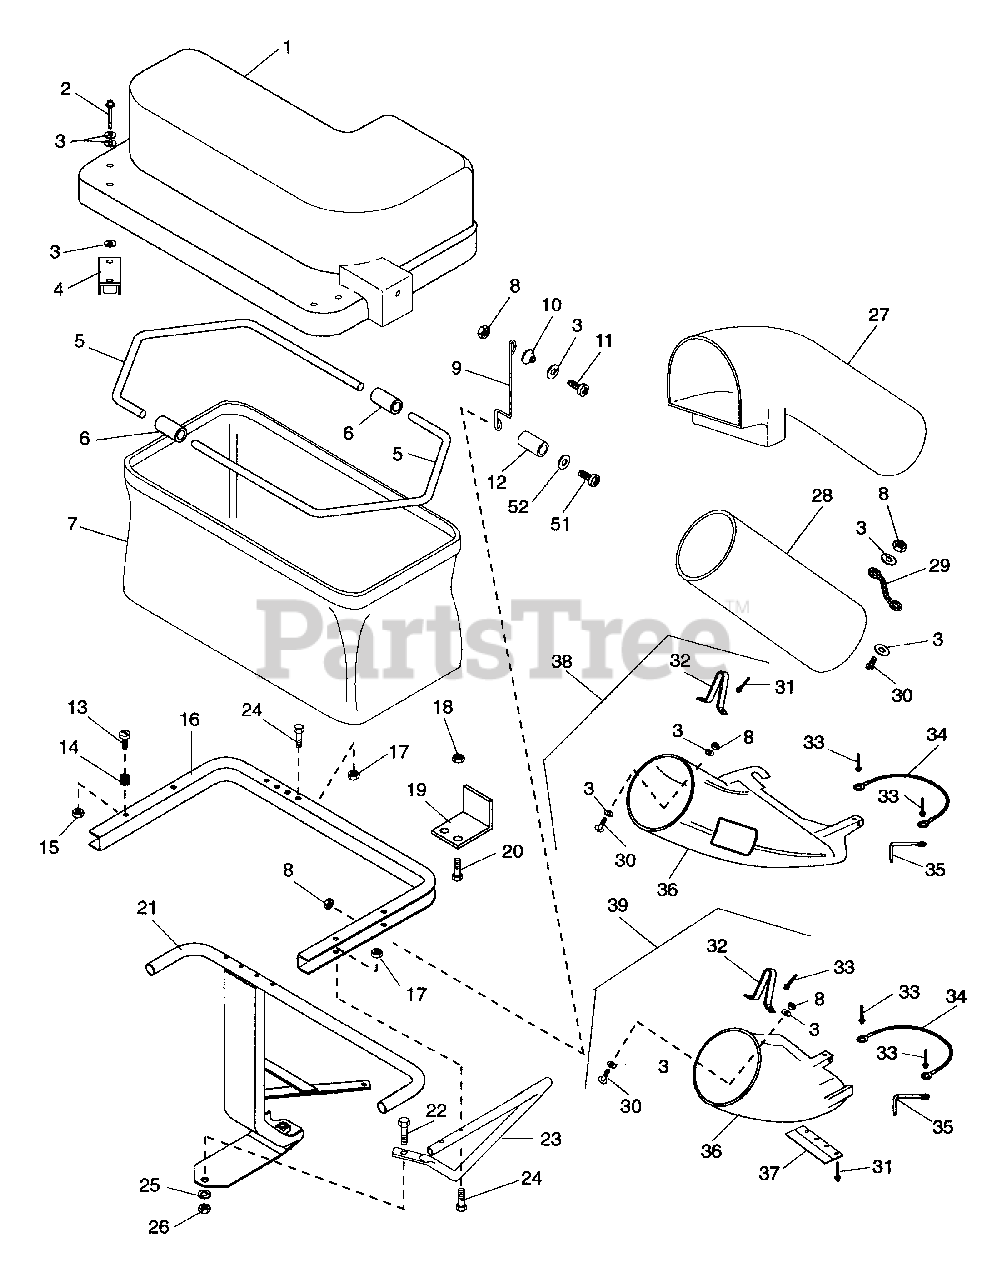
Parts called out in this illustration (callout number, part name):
1	COVER W/DECALS FOR 827013
1	COVER W/DECALS FOR 836005/006
2	RVT-POP .187X.402 DOME ST
3	WSHR-FL-STL .194X.492X.047 PL
6	CONNECTOR TUBE
8	NUT-KEPS 10-24 PL
9	LIFT ARM
10	BUSHING, HINGE
11	SCR-MCH 10-24X1.00 SLRH PL
12	SPLIT SPACER
13	SCR-MCH 6-32X.625
15	NUT-LK-MCH 6-32 W/INSERT
16	FRAME, BAG SUPPORT
17	NUT-LK .312-18 GR A PL
18	NUT-LK-CTR .250-20 PL
19	BRACKET, TUBE MOUNTING
20	BLT-HEX .25-20X.75 PL GR2
21	SUPPORT ASSEMBLY
22	BLT-HEX .50-13X1.00 PL GR2
23	SUPPORT, BAG
24	BLT-HEX .31-18X1.50 PL GR2
25	WSHR-LK .50 REG.
26	NUT .50-13 PL
27	BAGGER TUBE
28	TUBE EXTENSION
29	STRAP, RETAINER
30	SCR-MCH 10-24X1.00 RDHD
31	RVT-TBLR .187X.375 OH ST PL
32	CHUTE STRAP
33	RVT-TBLR .187X.375 ST-AL PL
34	LANYARD
35	PULL PIN
36	BOOT ASSEMBLY 40"
36	BOOT ASSEMBLY 28/32"
37	EXTENSION CHUTE
38	MOWER BOOT ASSEMBLY 28"/32"
39	MOWER BOOT ASSEMBLY 40"
